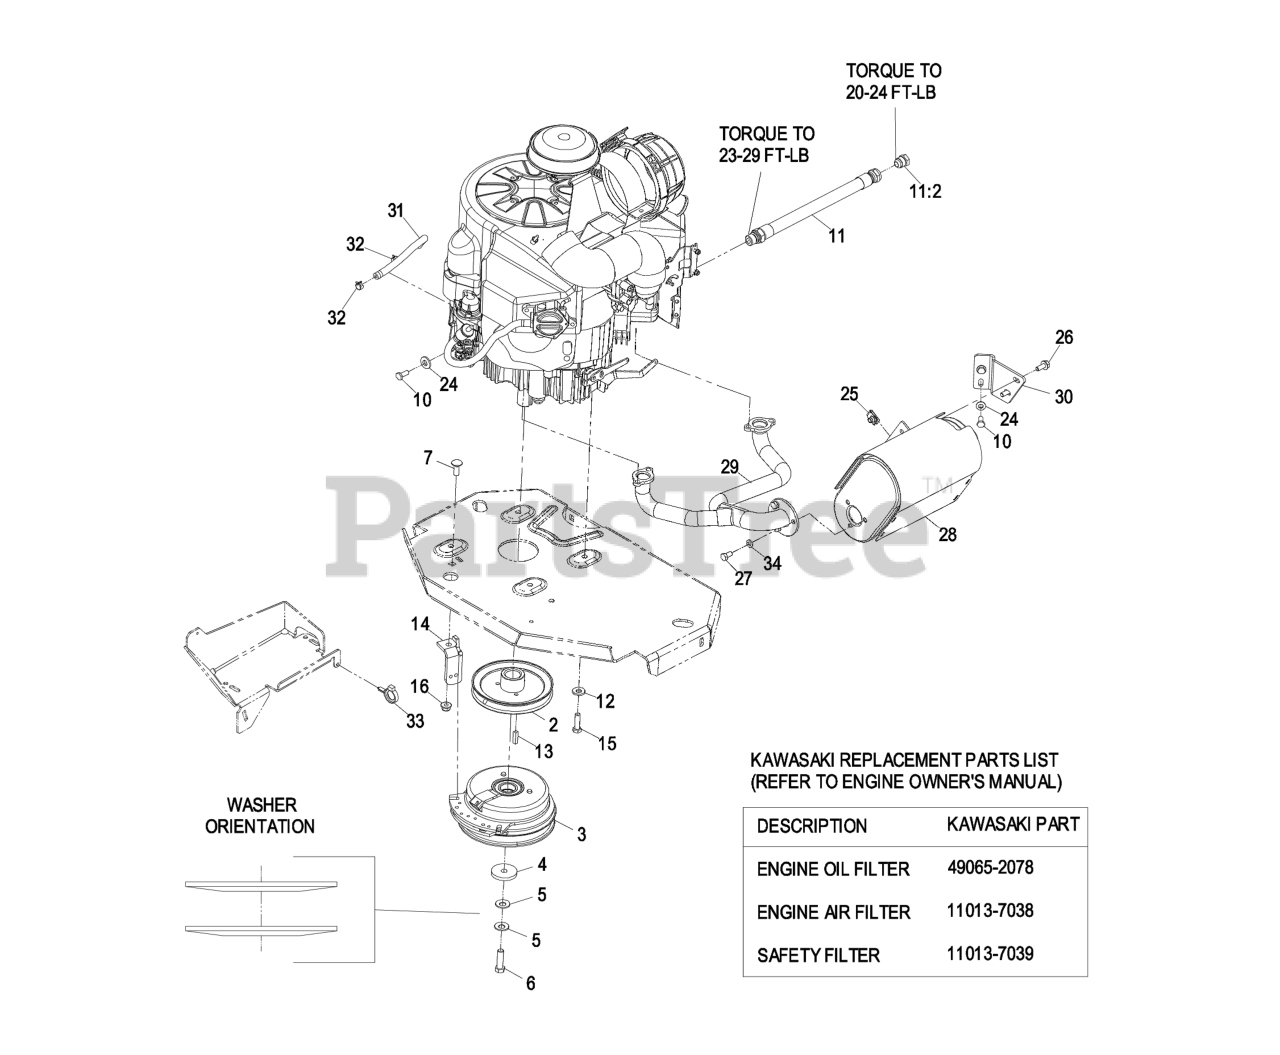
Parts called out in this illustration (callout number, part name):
2	SHEAVE
4	WASHER-CLUTCH
5	WASHER-SPRING
6	SCREW-HH 7/16-20 X 1 1/2 W/LOCTITE
7	SCREW-CARR
10	SCREW-HH
12	WASHER-BELLEVILLE
14	ANCHOR-CLUTCH
15	SCREW-HH
16	NUT-HF, NI
24	WASHER-SPRING
26	SCREW-HHF
27	SCREW-HH
28	MUFFLER-ENGINE
30	BRACKET-MUFFLER
31	HOSE-FUEL
32	CLAMP-HOSE
33	CLAMP-HOSE
34	WASHER-LOCK
